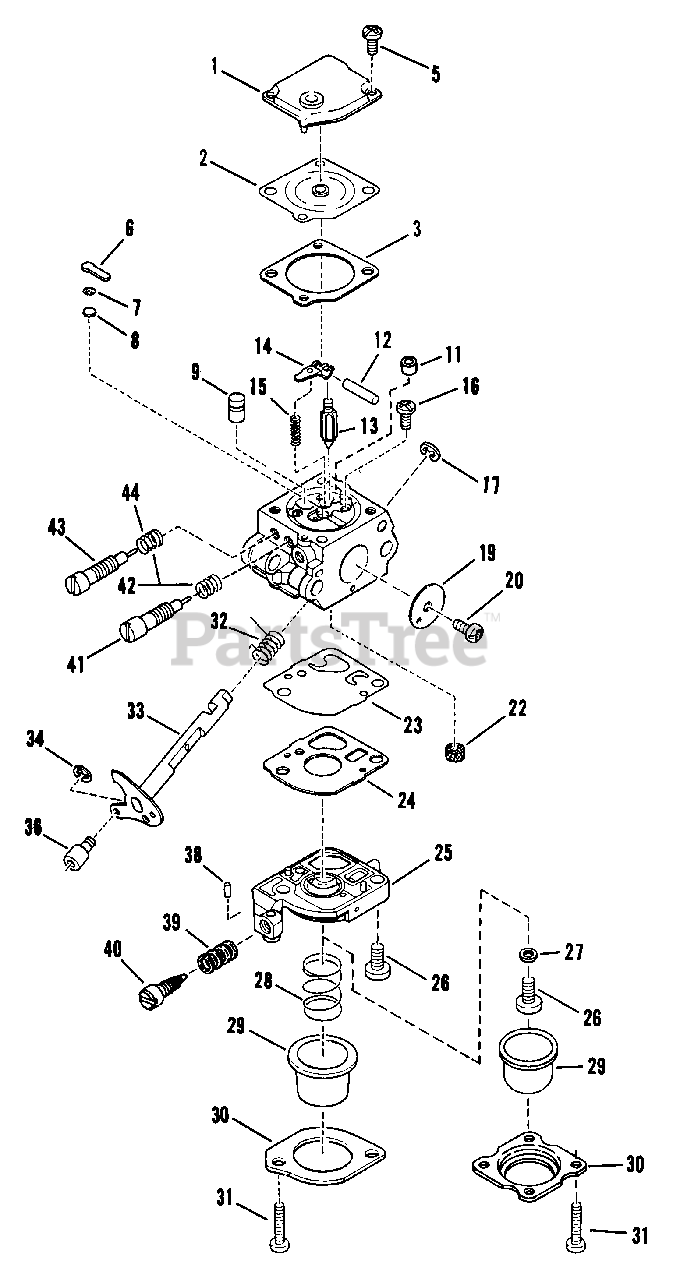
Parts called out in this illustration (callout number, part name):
1	COVER. Metering Chamber
2	DIAPHRAGM. Metering
3	GASKET. Metering Chamber
4	DISC
5	SCREW.Metering Cover
6	PLUG. Welch/Metering Chamber
7	RING. Screen Retainer
8	SCREEN. Check Valve
9	SEAT ASSY. Check Valve
10	SEAT ASSY. Check Valve
11	PLUG. Welch/Check Valve
12	Metering Lever
13	VALVE. Inlet Needle
14	LEVER. Metering
15	SPRING. Metering Lever
16	SCREW. Metering Lever
17	CLIP. Throttle Shaft
18	SCREW. Throttle Shaft Clip
19	VALVE. Throttle Plate
20	SCREW. Throttle Plate Valve
21	BULB. Primer Assy
22	SCREEN. Fuel Inlet
23	DIAPHRAGM. Fuel Pump
24	GASKET.Fuel Pump Cover
25	COVER. Fuel Pump
26	SCREW. Fuel Pump Cover
27	GASKET.Pump Cover Screw
28	SPRING. Primer Bulb
29	BULB. Primer
30	RETAINER. Primer Bulb
31	SCREW. Primer Bulb Retainer
32	SPRING, Throttle Return
33	SHAFT. Throttle
34	CLIP, Throttle Post
35	WASHER. Throttle Post
36	POST. Throttle Swivel
37	SCREW. Throttle Swivel Post
38	INSERT. Idle Adjust Friction
39	SPRING. Idle Adjusting Screw
40	SCREW. Idle Adjusting
41	SCREW. Idle Mix Needle
42	SPRING. Idle Mix Screw
43	SCREW. High Speed Mix
44	SPRING. High Speed Mix Screw
45	GASKET. Govenor
46	GOVENOR. Check Valve
47	ASSY. Air Purge Body
48	NUT. Primer Retainer
49	WASHER. Primer Retainer
